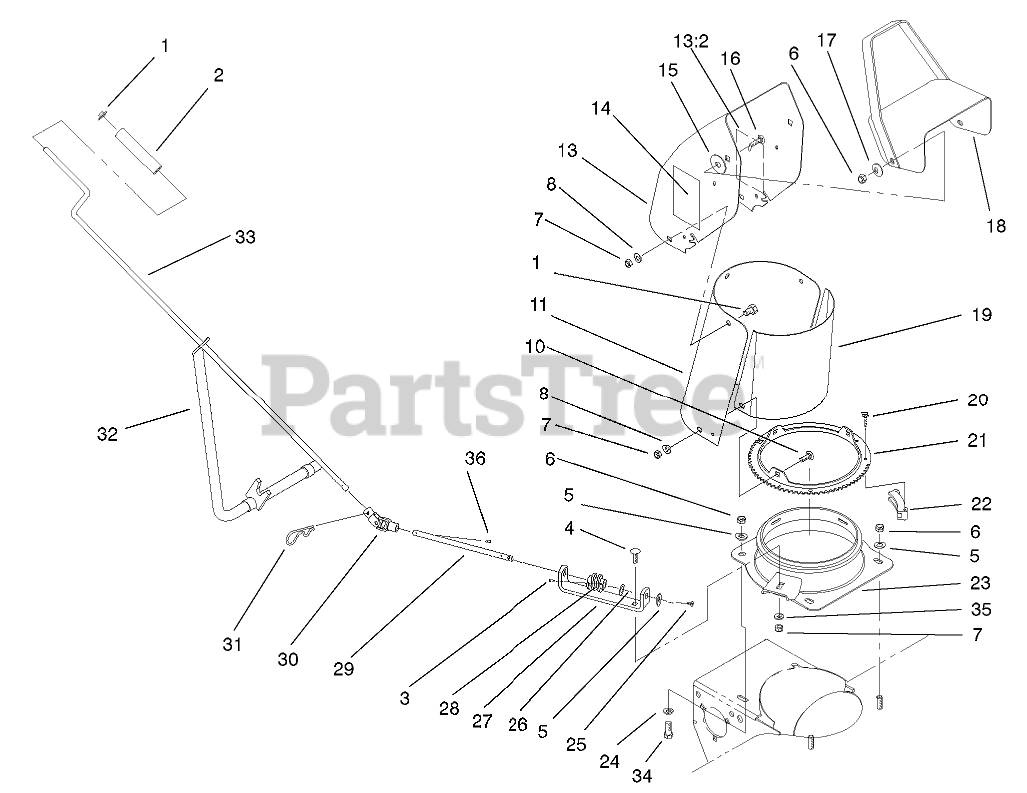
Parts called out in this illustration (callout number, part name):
1	RETAINER-PUSH ON
2	GRIP-CONTROL, CHUTE
3	PIN-SPRING
4	BOLT-CARR
5	WASHER-FLAT
6	NUT-LOCK, NI
7	NUT-LOCK, NI
8	WASHER-PLAIN
10	BOLT-CARR
11	EXTENDER-CHUTE, UPPER
12	SCREW-HH
13	CHUTE
13:2	DECAL-DANGER (only on: 38078)
14	DECAL-DISCHARGE DANGER
15	WASHER-RUBBER
16	BOLT-CARR
17	WASHER-BELLEVILLE
18	DEFLECTOR
19	SHIELD-DEFLECTOR
20	SCREW-SPECIAL
21	CHUTE SWIVEL RING
22	RETAINER-CHUTE
23	ADAPTER
24	WASHER-SPACER
25	PIN-COTTER
26	WASHER-SPRING
27	BRACKET-WORM
28	GEAR-WORM, CHUTE
30	JOINT-UNIVERSAL
31	PIN-HAIR
32	SUPPORT,ROD
33	ROD-CHUTE CONTROL
34	SCREW-HH
35	WASHER-LOCK
36	PIN-SPRING
